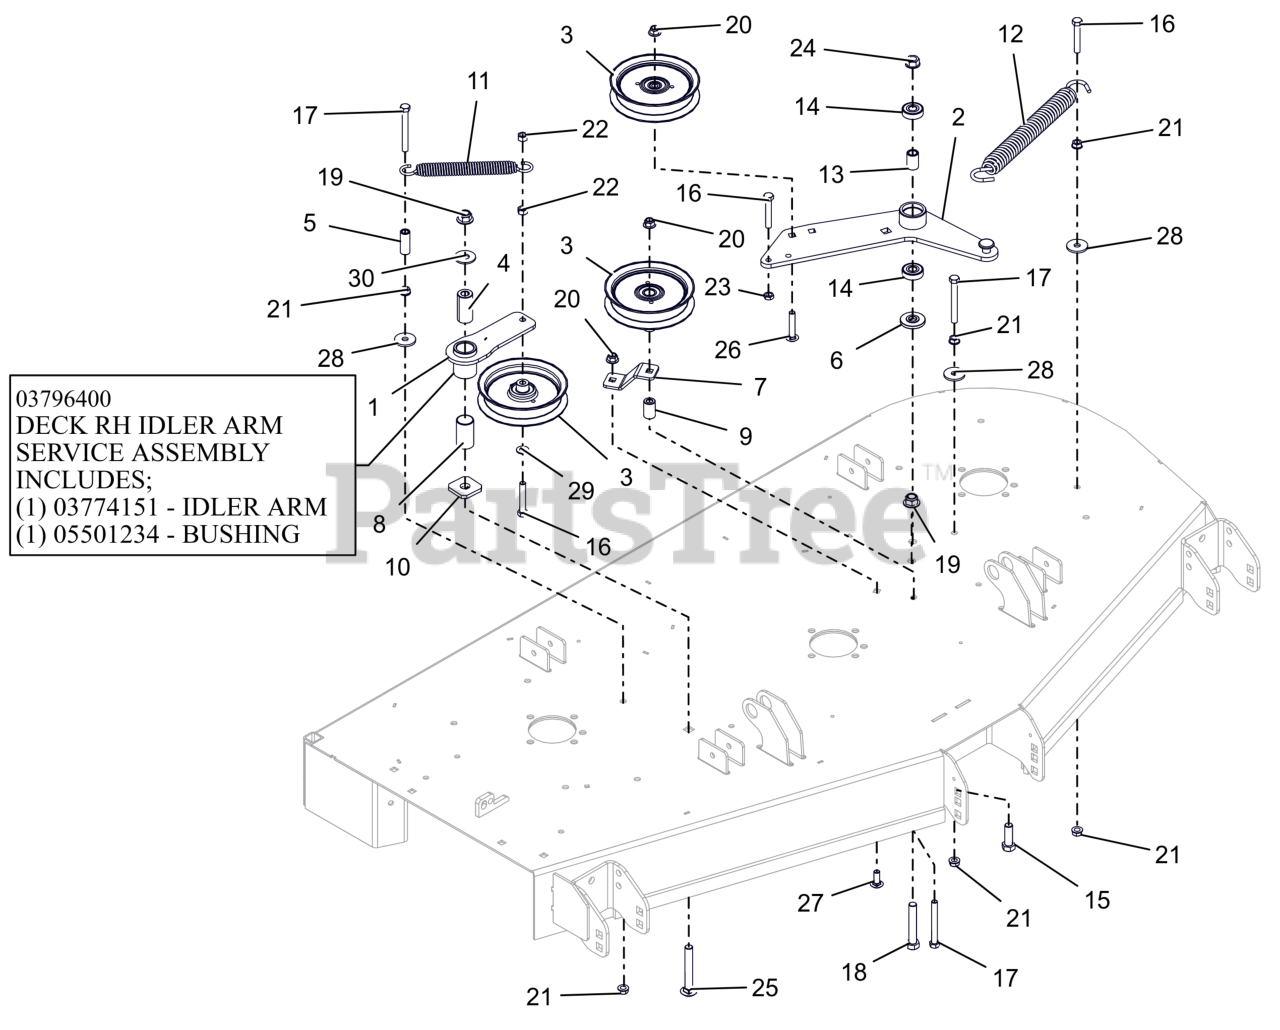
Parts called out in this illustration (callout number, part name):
1	WMT, IDLER ARM - BLACK
1	ASM, IDLER ARM (DECK)
2	DECK PTO IDLER ARM WLDMT - BLK
3	IDLER, FLAT 5.00"
4	BSHG, SPCR .502X.997X2.03 PM
5	SPACER, .375IDX.625ODX1.66 PM
6	SPACER, IDLER ARM
7	PTO FIXED IDLER MTG BRKT-ORG
8	BSHG, 1.00X1.125X1.937
9	BUSHING, SLV .380X.750X1.190
10	WSHR-FLT .640X1.75X.250
11	SPRING, EXTENSION
12	SPRING, EXTENSION
13	SPACER .510 X .75 X 1.1485
14	BRG-BALL .500X1.38X.437
15	BLT,HEX .50-13X1.50 G5 ZCC
16	BLT,HEX .38-16X2.25 G5 ZCC
17	BLT, HEX .38-16X3.25 G5 ZCC
18	BLT, HEX .50-13X3.00 G5 ZCC
19	NUT,NYL-FLG .50-13 GF ZCC
20	NUT,NYL-FLG .38-16 GF ZCC
21	NUT, SPNLK-FLG .38-16 G5 ZCC
22	NUT-LK-CTR .38-16 ZC120
23	NUT-JAM .375-16 G2 ZCC
24	NUT-LK-CTR-FLG .500-13 GG ZCC
25	BLT, RHSN .50-13X3.50 G5 ZCC
26	BLT,RHSSN.375-16X2.00 G5 ZCC
27	BLT,RHSSN .38-16X1.00 G5 ZCC
28	WSHR,FLT .406X1.375X.135 ZCC
29	WSHR,FLT .406X.812X.065 ZCC
30	WSHR,FLT .563X1.375X.109 ZCC
